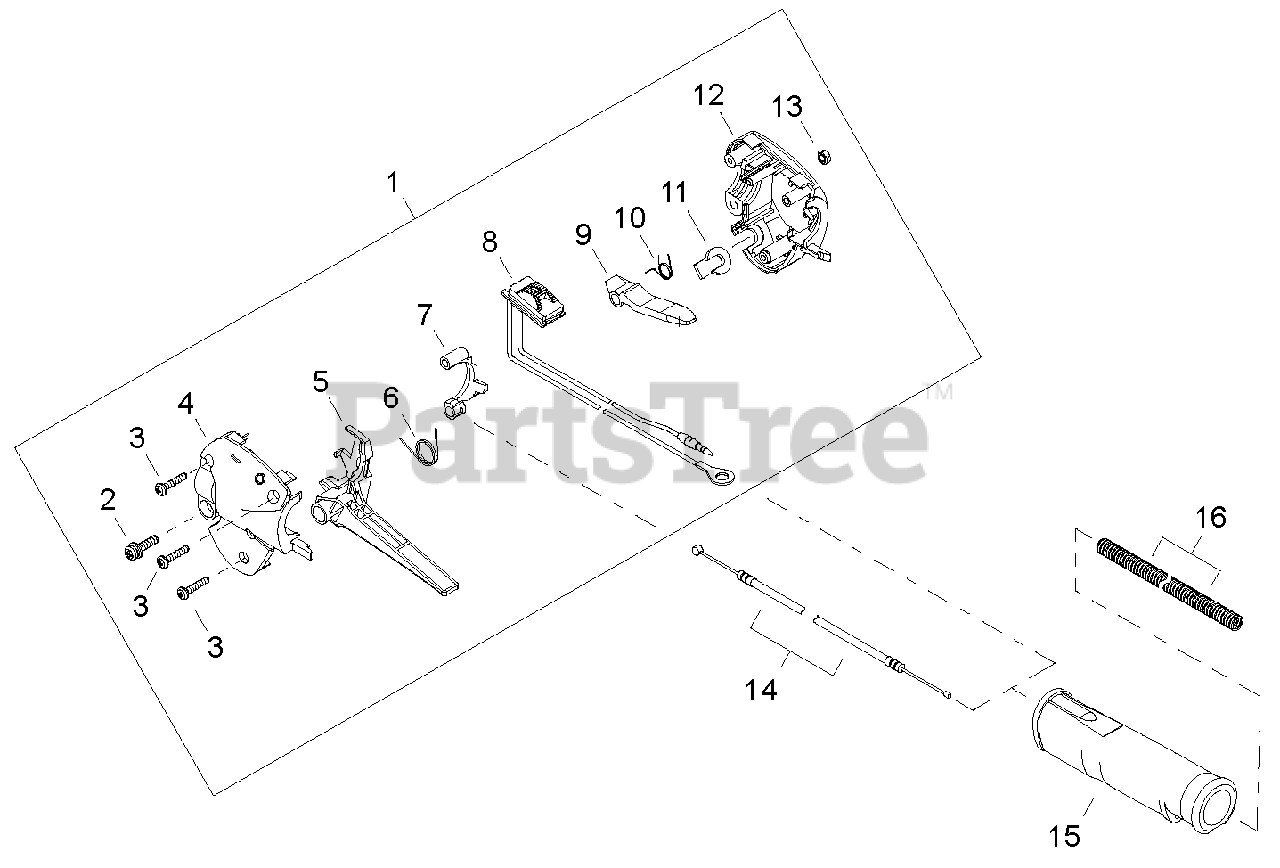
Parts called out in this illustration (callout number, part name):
2	SCREW M5×20
3	SCREW, TAPPING M4×20
4	CONTROL HANDLE - LEFT
5	TRIGGER, THROTTLE
6	SPRING, THROTTLE RETURN
7	LOCKOUT, THROTTLE
8	SWITCH, ON-OFF
9	LEVER, THROTTLE LOCKOUT
10	SPRING, THROTTLE LOCKOUT
11	PLUG
12	CONTROL HANDLE - RIGHT
12-1	THROTTLE CONTROL ASSY
13	NUT M5
14	CABLE, THROTTLE
15	GRIP, REAR
16	TUBE, PLASTIC PROTECTIVE
